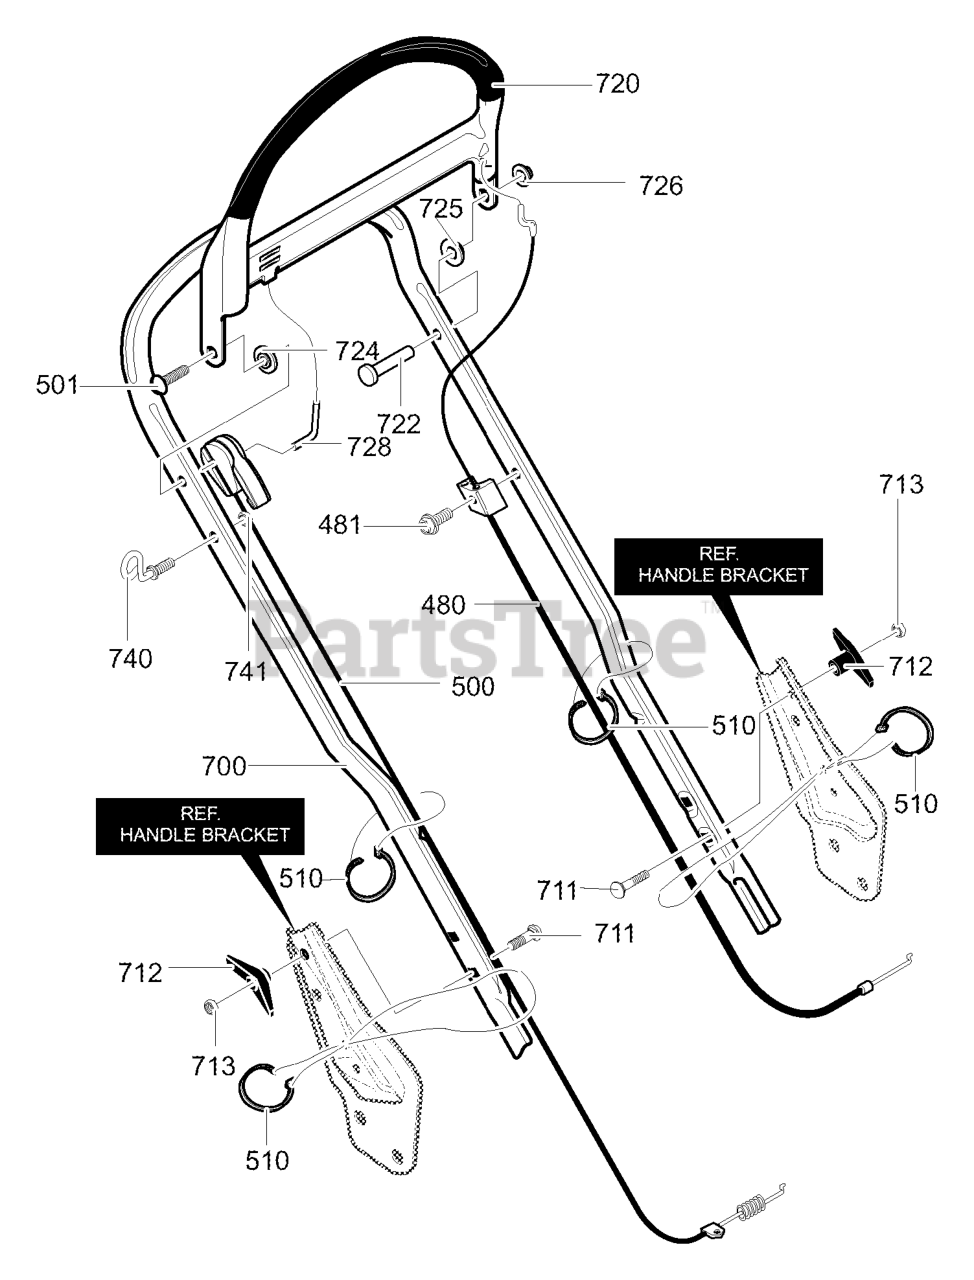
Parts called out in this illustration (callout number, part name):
480	CABLE,STOP
481	SCREW, 10-16X.75 S
500	CABLE, DRIVE
501	SCREW,#10-16X1.38
510	TIE, CABLE BLACK NYLON 5.62L
516	SCREW,10-16X.50HWASEMTAP
700	HANDLE
711	BOLT, 5/16-18X2.00
712	KNOB, T W/516/18 NUT
713	NUT, 5/16-18 REGHEX
720	LEVER, STOP FLAT
722	PIN, CLEVIS
726	RETAINER CAP
728	ROD, LINK
740	GUIDE, ROPE 1/4-20
741	NUT, 1/4-20
